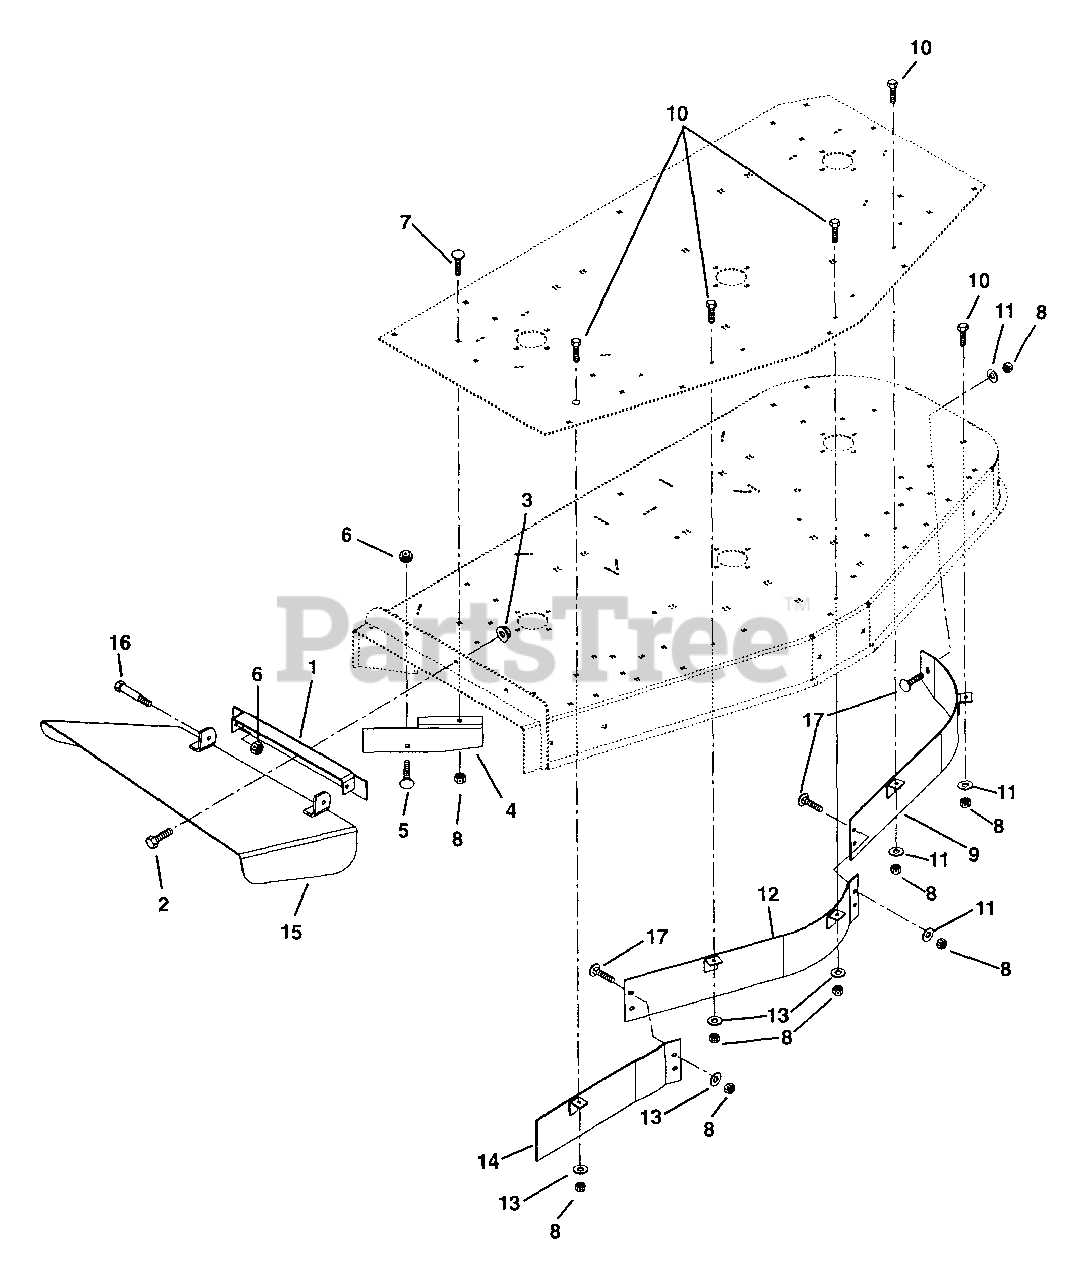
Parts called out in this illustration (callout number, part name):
1	Weldment, Discharge Chute Bracket
2	Bolt-Hex .38-16 x 1.00 Grade 5
3	Nut-Locking-Flange .38-16
4	Deflector, 72"
5	Bolt-Round Head Square Neck .38-16 x 1.00 Grade 2
6	Nut-Locking-Center .38-16
7	Bolt-Round Head Square Neck .31-18 x 1.00 Grade 5
8	Nut-Locking-Nylon .31-18
9	Weldment, 72" Left Hand Baffle
10	Bolt-Hex .31-18 x 1.00 Grade 5
11	Washer-Flat-Steel .312 x .734 x .065
12	Weldment, 72" Center Baffle
13	Washer-Flat-Steel .312 x .734 x .065
14	Weldment, 72" Right Hand Baffle
15	Weldment, Discharge Chute 72"
16	Bolt-Shoulder .38-16 x .38
17	Bolt-Round Head Square Neck .31-18 x .75 Grade 2
